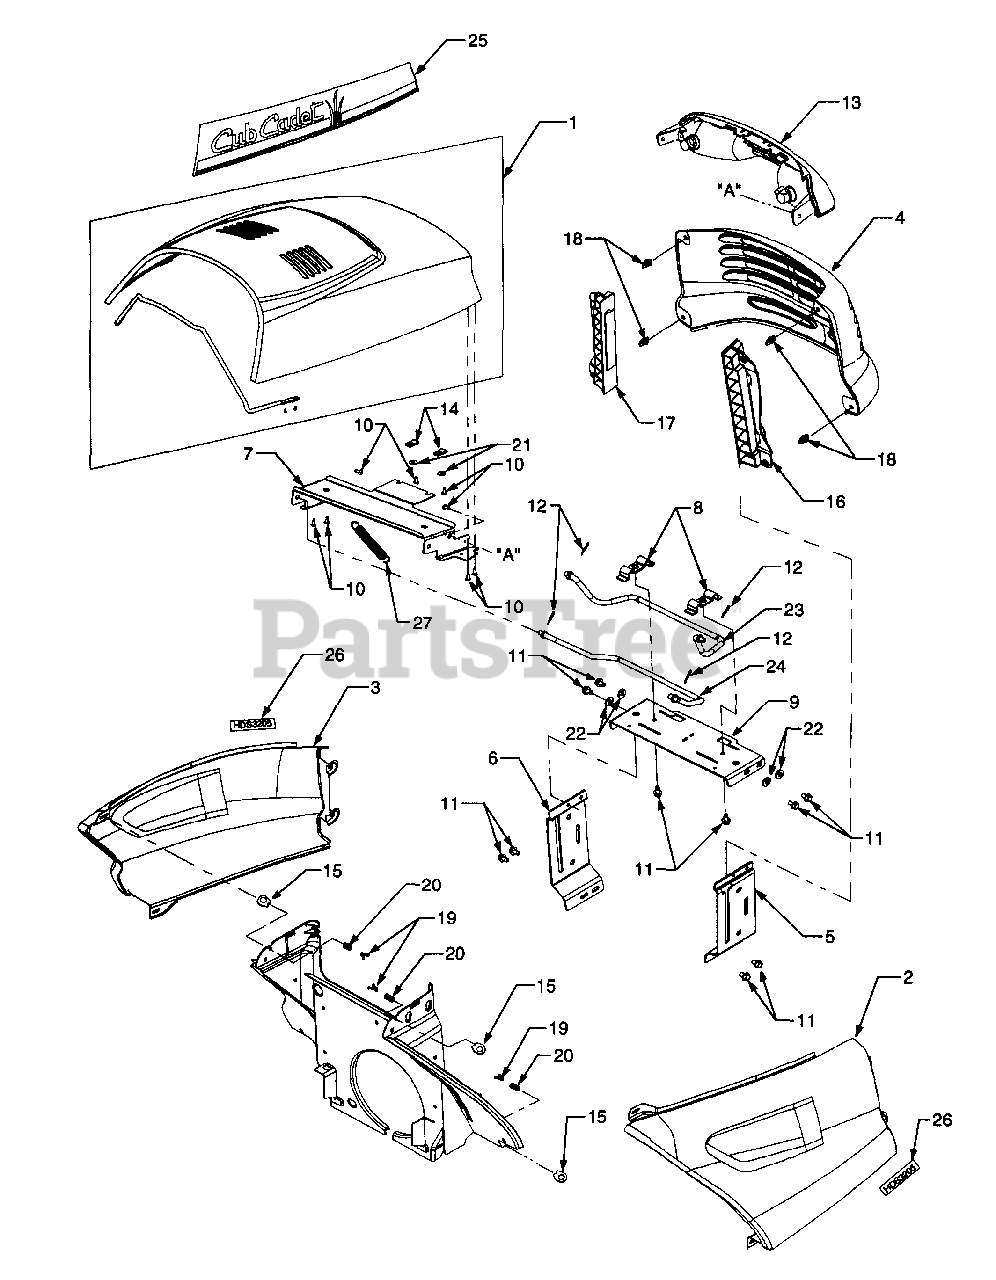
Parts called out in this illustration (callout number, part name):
1	Hood w/Support Rod Assembly
2	Side Panel, RH
3	Side Panel, LH
4	Grille, Series 3000
5	Support, Grille - RH
6	Support, Grille - LH
7	Bracket, Upper Hood
8	Bracket, Rod Retainer
9	Support, Hood
10	Screw, Truss Hd, Tapp, #10-16 x .5
11	Screw, Hex Wash. Hd. Tapp 5/16-18 x .5
12	Pin, Internal Cotter
13	Headlight Assembly
14	Nut, U-type Speed, #10
15	Latch, 1/4 Turn
16	Mount, Side Panel/Grille RH
17	Mount, Side Panel/Grille LH
18	Fastener, Grille Mount
19	Clip, Spring
20	Spring, Compression
21	Washer, Flat, .194 x .62 x .063
22	Washer, Flat, .344 x .75 x .120
23	Rod, Upper Hood
24	Rod, Upper Hood
25	Graphic, Hood - RH
26	Graphic, HDS 3205
27	Spring, Extension
